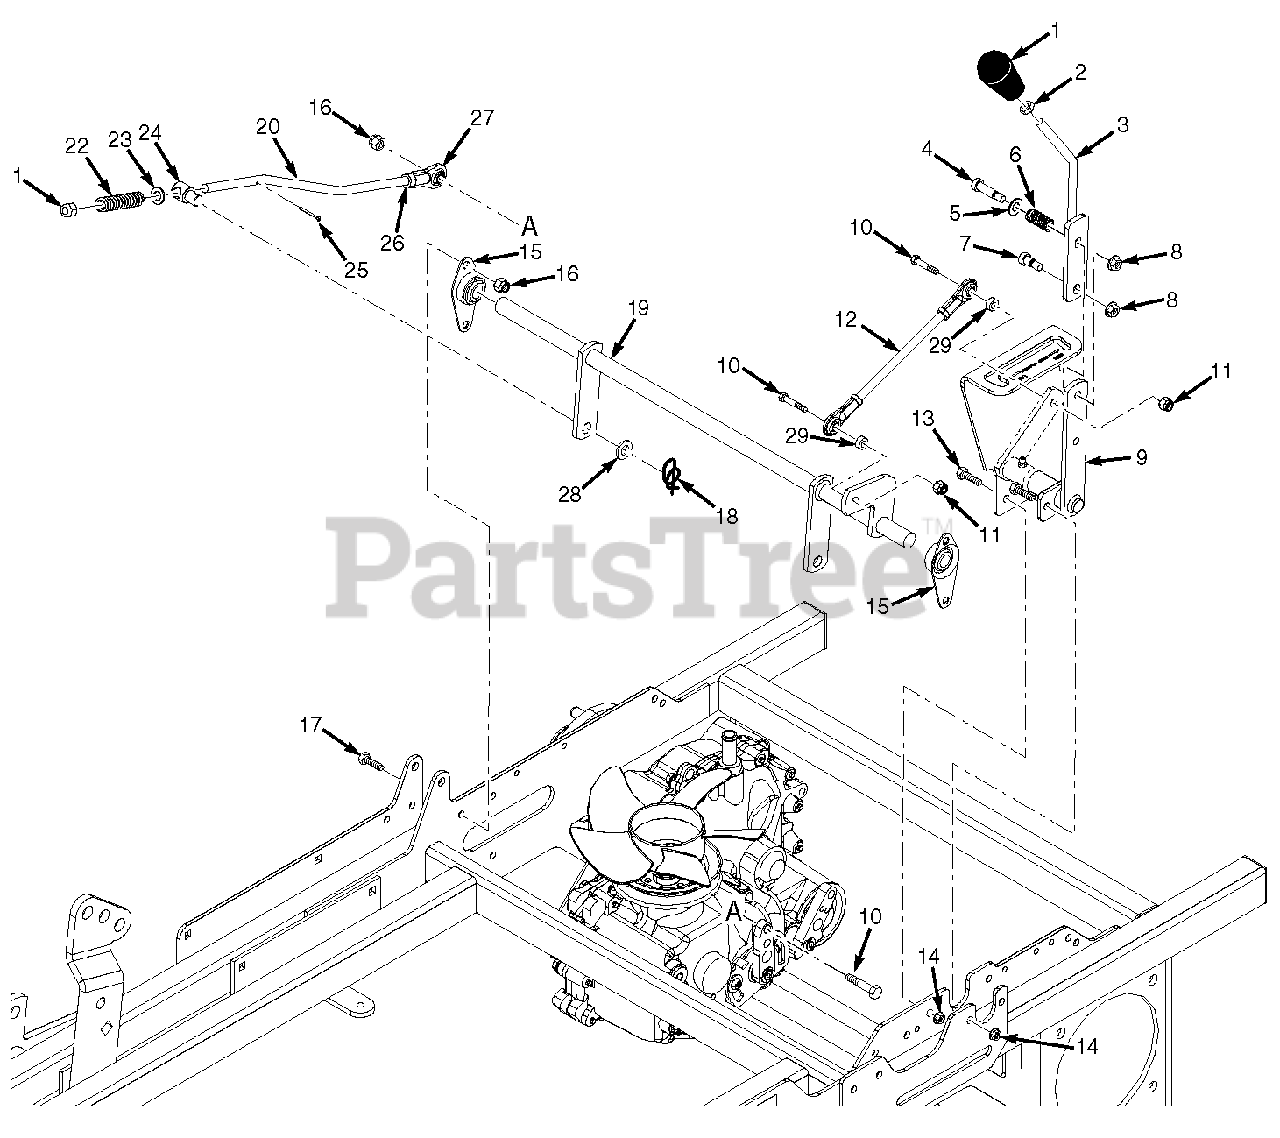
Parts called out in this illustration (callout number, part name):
1	Knob, Soft Touch
2	Nut, Jam 3/8-16 UNC
3	Lever Weldment, Speed Control SCZ
4	Bolt, Shoulder 3/8 x 1"
5	Flatwasher, 3/8-.406 x .812 x .065
6	Spring, Speed Control
7	Bolt, Shoulder 3/8 x 3/8"
8	Nut, Serrated Flange 5/16-18
9	Control Weldment, Speed Range Adjust
9	Grease Fitting, 1/4-28 Self Tap
10	Bolt, Hex Head 3/8-16 x 1-1/2"
11	Nut, Elastic Stop 3/8-16
12	Linkage Assembly, Upper Speed Control
12	Rod End, 3/8-24 RH
12	Nut, Jam 3/8-24 UNF
12	Rod End, 3/8-24 LH
12	Nut, Jam 3/8-24 UNF LH
13	Bolt, Hex Head 5/16-18 x 1"
14	Nut, Flange Head Elastic Stop 5/16-18
15	Bearing, Self Align
16	Nut, FLG HH Elastic Stop 5/16-18
17	Bolt, Hex Head 5/16-18 x 3/4"
18	Pin, Rue Cotter 1/2" Dia.
19	Speed Control Bellcrank Weldment
20	Rod, Speed Linkage
21	Nut, Elastic Stop 3/8-24
22	Spring
23	Flatwasher, 3/8-.406 x .734 x .063
24	Bushing, Pivot
25	Cotter Pin
26	Nut, 3/8-24 UNF Jam
27	Rod End, 3/8-24
28	Flatwasher, 3/8-.391 x .938 x .105
29	Spacer
